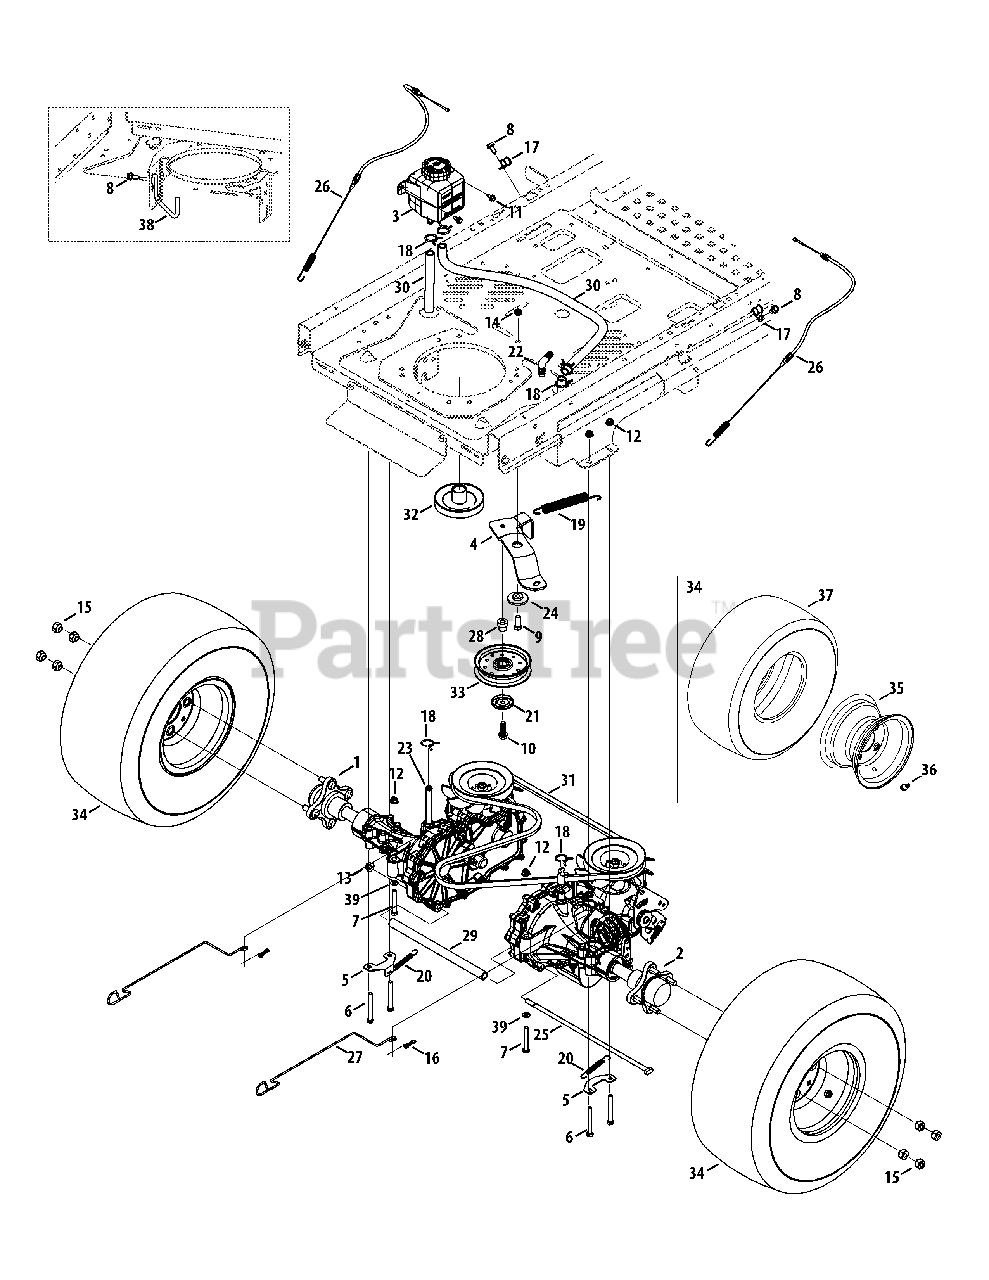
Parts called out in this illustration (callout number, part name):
1	Transmission Assembly, LH
2	Transmission Assembly, RH
3	Expansion Tank Assembly
4	Idler Bracket
5	Brake Mounting Bracket
6	Hex Screw, 5/16-18 x 2.75
7	Hex Cap Screw, 5/16-18 x 2.25
8	Hex Washer Screw, 5/16-18 x .750
9	Hex Screw, 3/8-16 x 1.00
10	Hex Washer Screw, 3/8-16 x 1.250
11	Hex Washer Screw, 1/4-20 x .625
12	Flange Lock Nut, 5/16-18
13	Flange Lock Nut, 3/8-16
14	Jam Lock Nut, 3/8-16
15	Lug Nut, 7/16-14
16	Bow-Tie Cotter Pin
17	Clamp 9/16 Dia.
18	Hose Clamp, .75 Dia. x .312
19	Extension Spring, .75 Dia. x 6.02
20	Extension Spring, .38 OD x 3.25 LG
21	Pulley Cap
22	Elbow, 90
23	Fitting, 9/16, Barb
24	Shoulder Spacer, .884 x .190
25	Rod, .337 Dia. x 14.75 LG
26	Park Brake Cable
27	Bypass Rod
28	Shoulder Spacer
29	Spacer, .75 OD x 11.31 LG
30	Fuel Hose, 1/2 ID
31	Belt, A-Type x 67.0
32	Engine Pulley
33	Idler Pulley, 4.25 Dia.
34	Complete Wheel, 20 x 10-8
36	Valve Tubeless
37	Tire Only
38	Engine Keeper Rod
39	Flat Washer .330 ID x .630 OD
